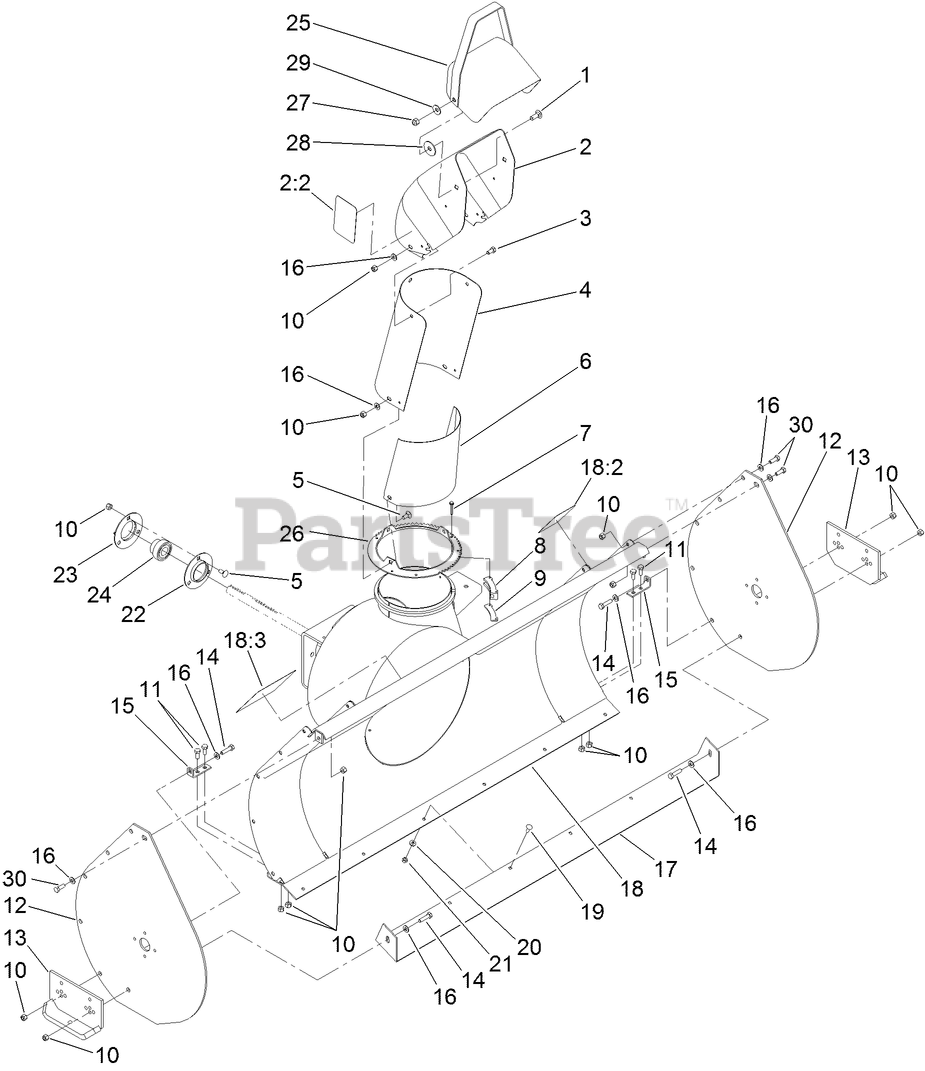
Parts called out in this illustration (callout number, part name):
1	BOLT-CARR
2	DISCHARGE CHUTE ASM
2:2	DECAL-DANGER, DISCHARGE
3	SCREW-HH
4	EXTENDER-CHUTE, UPPER
5	BOLT-CARR
6	SHIELD-DEFLECTOR
7	SCREW-HWH
8	RETAINER-CHUTE
9	PLATE-RETAINER, CHUTE
10	NUT-LOCK, NI
11	SCREW-HH
12	PLATE-SIDE
13	SKID ASM
14	SCREW-HH
15	BRACKET-SUPPORT, BLADE
16	WASHER-PLAIN
17	BLADE-SCRAPER
18	HOUSING ASM
18:2	DECAL-DANGER, AUGER
18:3	DECAL-WARNING
19	SCREW-CARR
20	WASHER-FLAT
21	NUT-LOCK, NI
22	Flange
23	FLANGE-RELUBE
24	BEARING AND COLLAR
25	DEFLECTOR
26	RING-SWIVEL, CHUTE
27	NUT-LOCK, NI
28	WASHER-RUBBER
29	WASHER-BELLEVILLE
30	SCREW-HH
